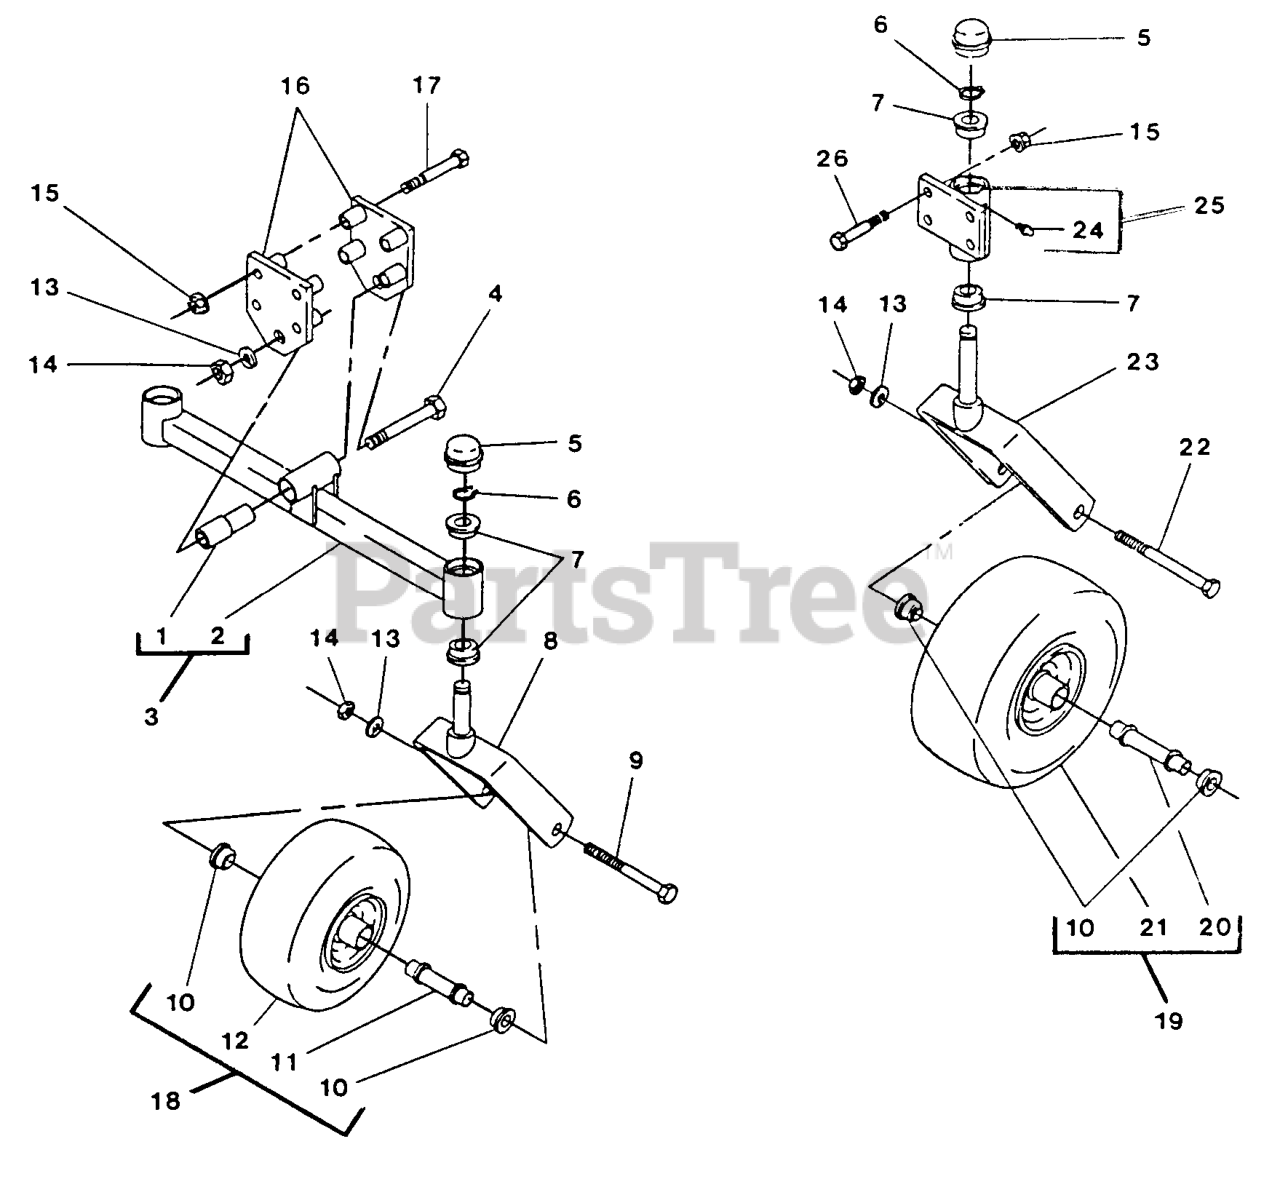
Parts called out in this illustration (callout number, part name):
5	CAP,GREASE
7	BEARING,FLANGED
11	WLD,WHEEL SPACER
18	ASM,CASTER WHEEL
20	SPACER WLDMT,WHEEL
23	WLD,CASTER FORK
25	WLD,CASTER MOUNT
